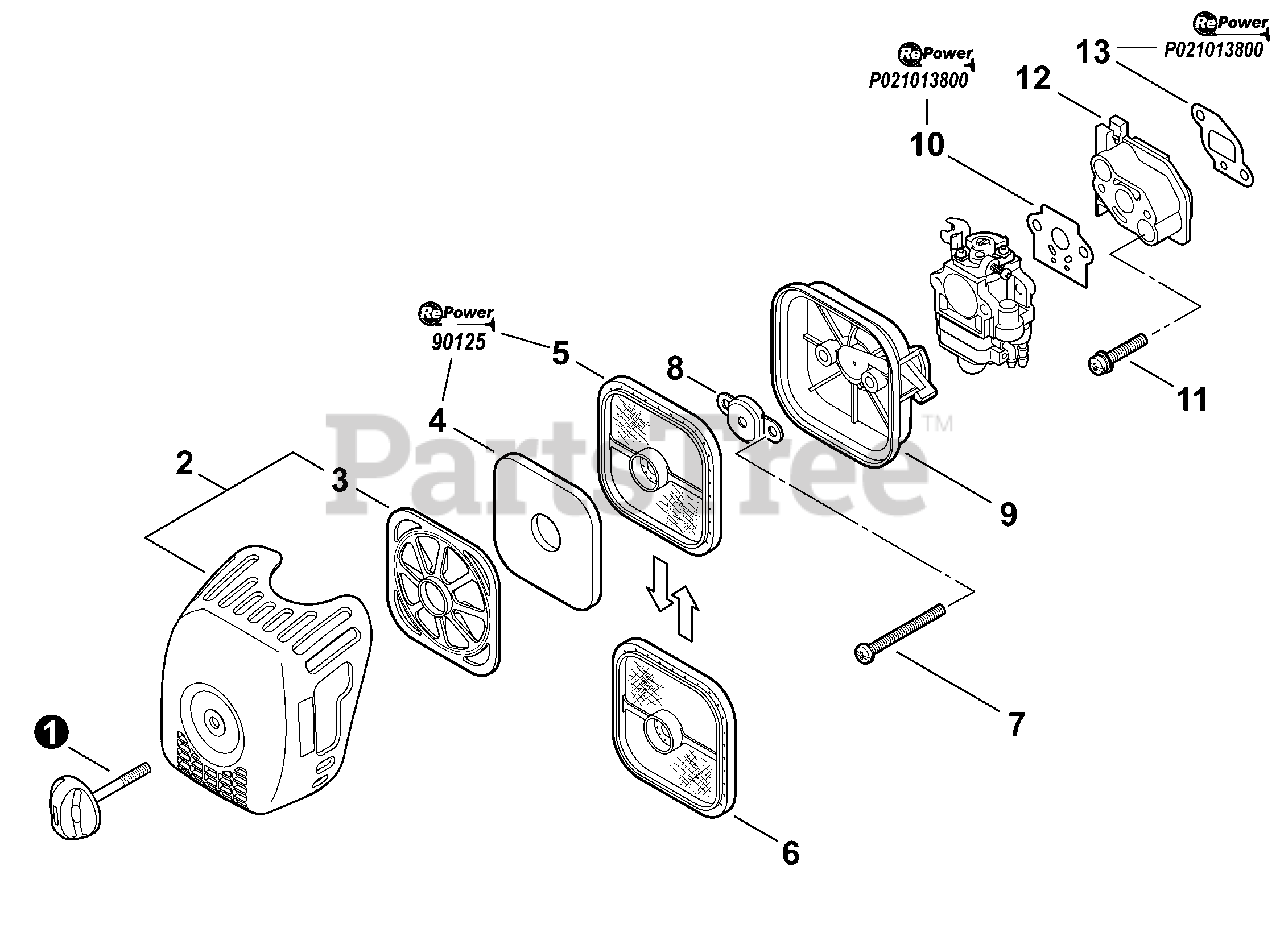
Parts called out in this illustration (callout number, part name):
1	THUMBSCREW
2	COVER KIT, AIR FILTER
3	RETAINER, PRE-FILTER
4	PRE-FILTER, FOAM
5	FILTER, AIR - DOUBLE LAYER
6	FILTER, AIR - SINGLE LAYER
7	SCREW 5×60
8	PLATE, PREVENT
9	CASE, AIR FILTER
10	GASKET, INTAKE
11	BOLT 5×30
12	INSULATOR, INTAKE
13	GASKET, INTAKE
